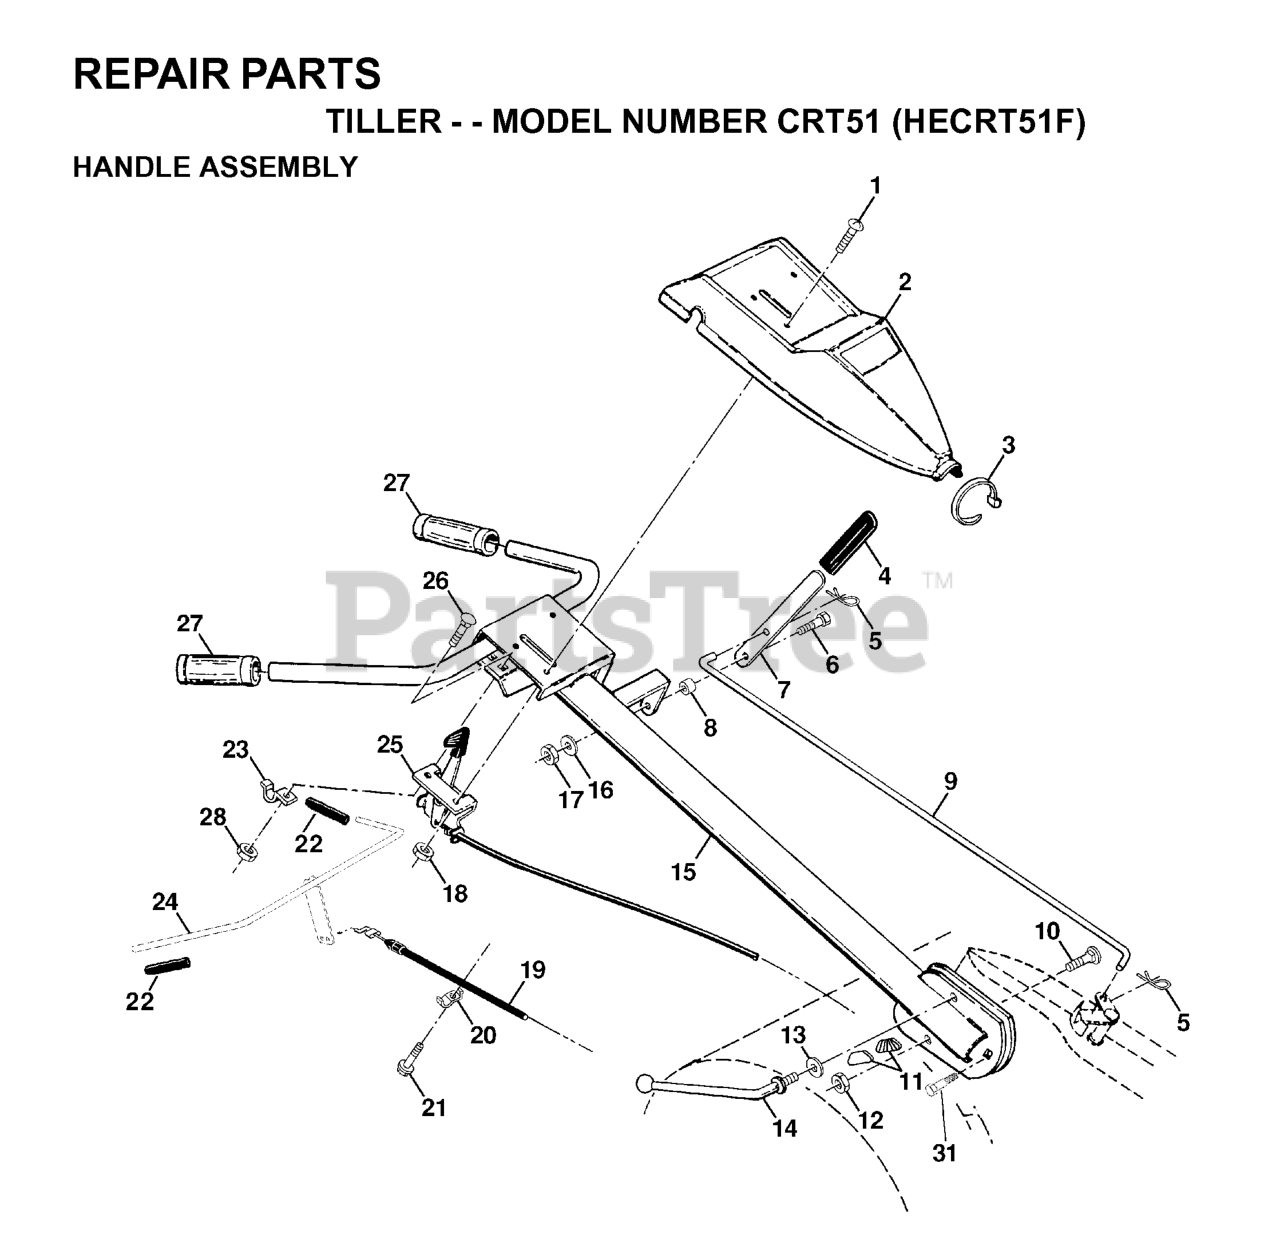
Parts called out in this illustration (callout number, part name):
1	SCREW.PNHD.10-24
3	TIE CABLE CRT
4	GRIP T
5	RETAINER M
6	SHOULDER BOLT ST
7	SHIFT HANDLE CRT
8	GROMMET.RUBBER.CRT.TILLER
9	SHIFT ROD CRT
10	BOLT D
11	LOCK.HANDLE.CRT
12	LOCKNUT
13	WASHER CRT
14	LEVER.LOCK.CRT
15	HANDLE
16	LOCKWASHER
17	NUT
18	NUT **
19	CABLE.CLUTCH
20	CONDUIT.CLIP.PLATED
21	TAPPING SCREW
22	GRIP BAR CRT(1)
23	CLAMP.BAR.CRT.BLACK
24	CONTROL BAR ASSY
25	CONT,THROTTLE
27	KIT.GRIP.HANDLE.5.00.BLK.VINYL
31	BOLT.PIVOT
